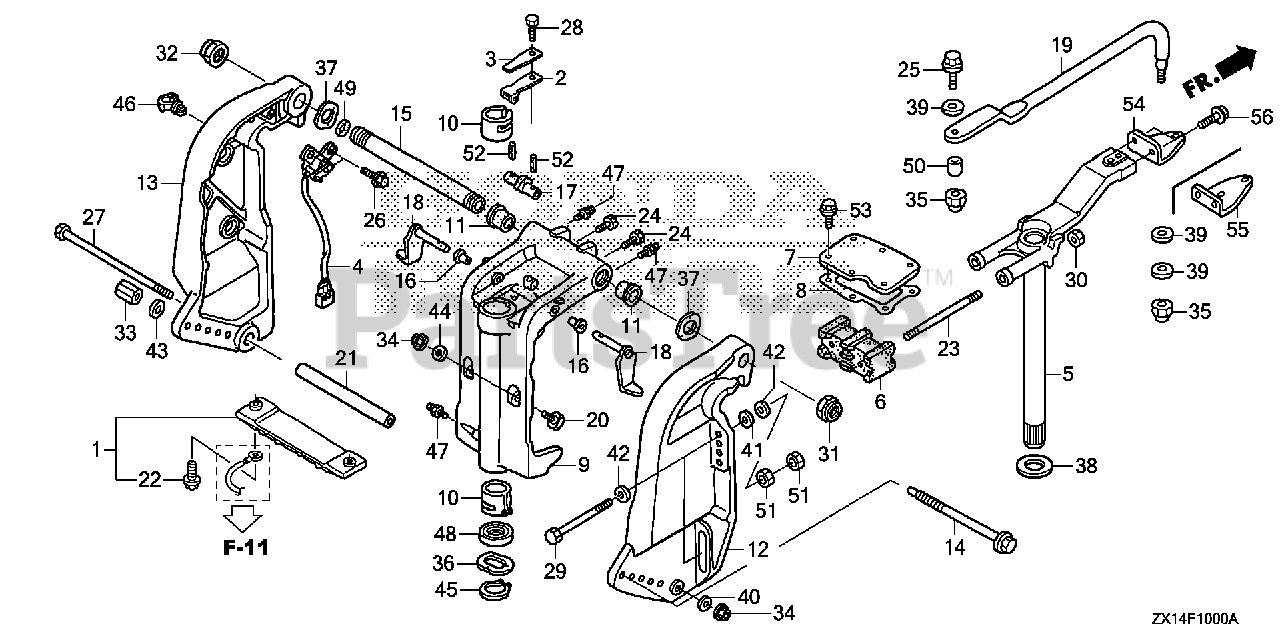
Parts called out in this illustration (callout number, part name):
1	METAL KIT, ANODE Use from Frame SN 4800343.
2	SPRING, CLICK
3	SPRING, CLICK ASSIST
4	SENSOR ASSY., TRIM ANGLE
5	FRAME, MOUNTING
6	MOUNT, RUBBER (UPPER)
7	HOLDER, MOUNTING (UPPER)
8	GASKET, MOUNTING HOLDER (UPPER)
9	CASE, SWIVEL *NH282MU* (OYSTER SILVER METALLIC-U)
10	LINER, SWIVEL CASE
11	BUSH, SWIVEL CASE
12	BRACKET, R. STERN *NH282MU* (OYSTER SILVER METALLIC-U)
13	BRACKET, L. STERN *NH282MU* (OYSTER SILVER METALLIC-U)
14	ROD, ADJUSTING
15	SHAFT, TILTING
16	BUSH, TILT ARM
17	BRACKET, TILTING
18	STOPPER, TILT
19	ROD, STEERING
20	RECEIVER, THRUST
21	COLLAR, CYLINDER (LOWER)
22	BOLT, FLANGE (6X23) Use from Frame SN 4800343.
23	BOLT, STUD (12X150)
24	BOLT (1/4-28UNF)
25	BOLT (3/8-24UNF)
26	BOLT, FLANGE (6X20) (ENGINE NO.)
27	BOLT, HEX. (10X235)
28	BOLT, HEX. (6X14)
29	BOLT, HEX. (12X119)
30	NUT, FLANGE (12MM)
31	NUT, SELF-LOCK (7/8-14UNF)
32	NUT, SELF-LOCK (M25X2.0)
33	NUT, ADJUSTER ROD
34	NUT, FLANGE (10MM)
35	NUT, SELF-LOCK (3/8-24UNF)
36	WASHER, WAVE (40MM)
37	WASHER, WAVE (26MM)
38	WASHER, THRUST (34MM)
39	WASHER (10MM)
40	WASHER, PLAIN (10MM)
41	WASHER, PLAIN (12MM)
42	WASHER, PLAIN (12MM)
43	WASHER, PLAIN (12MM)
44	WASHER, PLAIN (10MM)
45	CIRCLIP (OUTER) (39MM)
46	CLIP, WIRE HARNESS
47	NIPPLE, GREASE
48	OIL SEAL (39.5X52X6) (ARAI)
49	O-RING (15.54X2.26)
50	COLLAR, STEERING ROD
51	NUT, HEX. (12MM)
52	PIN, SPRING (2.5X20)
53	BOLT, FLANGE (8X35)
